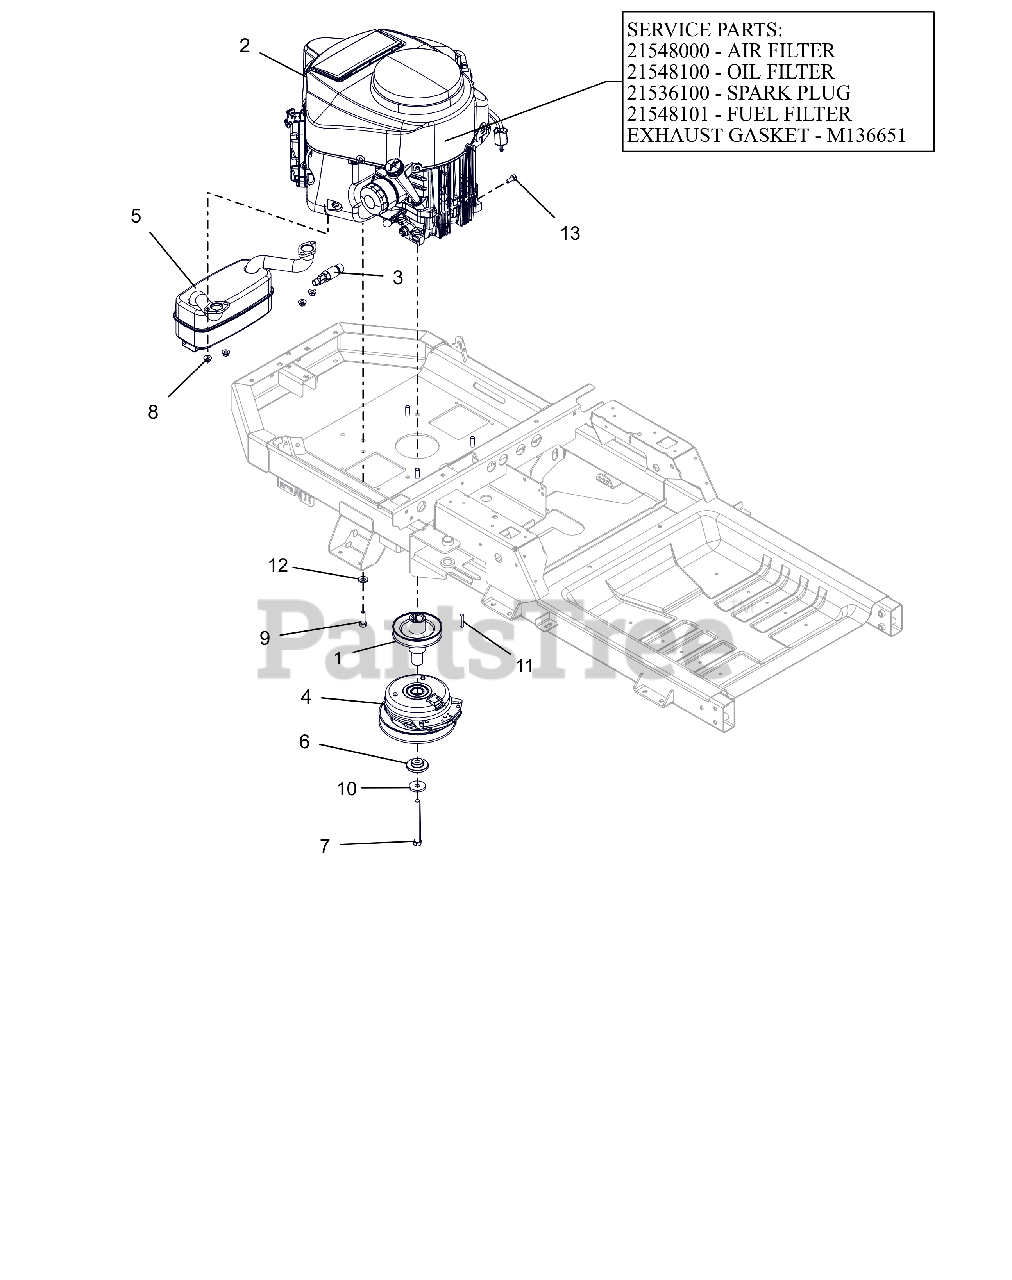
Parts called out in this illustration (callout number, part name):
1	WLDMT, DRIVE SHEAVE-X
2	ENGINE, KAWASAKI FR691 23HP
2	AIR FILTER, KAWASAKI FR
2	OIL FILTER, KAWASAKI FR
2	PLUG, SPARK
2	FUEL FILTER-KAWASAKI FR
2	GASKET, MUFFLER #
3	DRAIN, OIL M20X2.5
4	CLUTCH,105FTLB MONOPOLE 6.83"
5	MUFFLER - KAWASAKI
6	BSHG-FLG .469X1.06X.574X2.0
7	BLT, HEX .44-20X4.50 G8 ZCC NT
8	NUT-LK-TOP-FLG M8 ZCC
9	BLT, HEX .38-16X1.25 G5 ZCC NT
10	WASHER, 7/16" SPRING DISK
11	KEY-SQ .25 X 1.25 X .25 SAE
12	WASHER, 3/8" SPRING DISC
13	BLT, HEX M8-1.25X20 G8.8 ZCC
